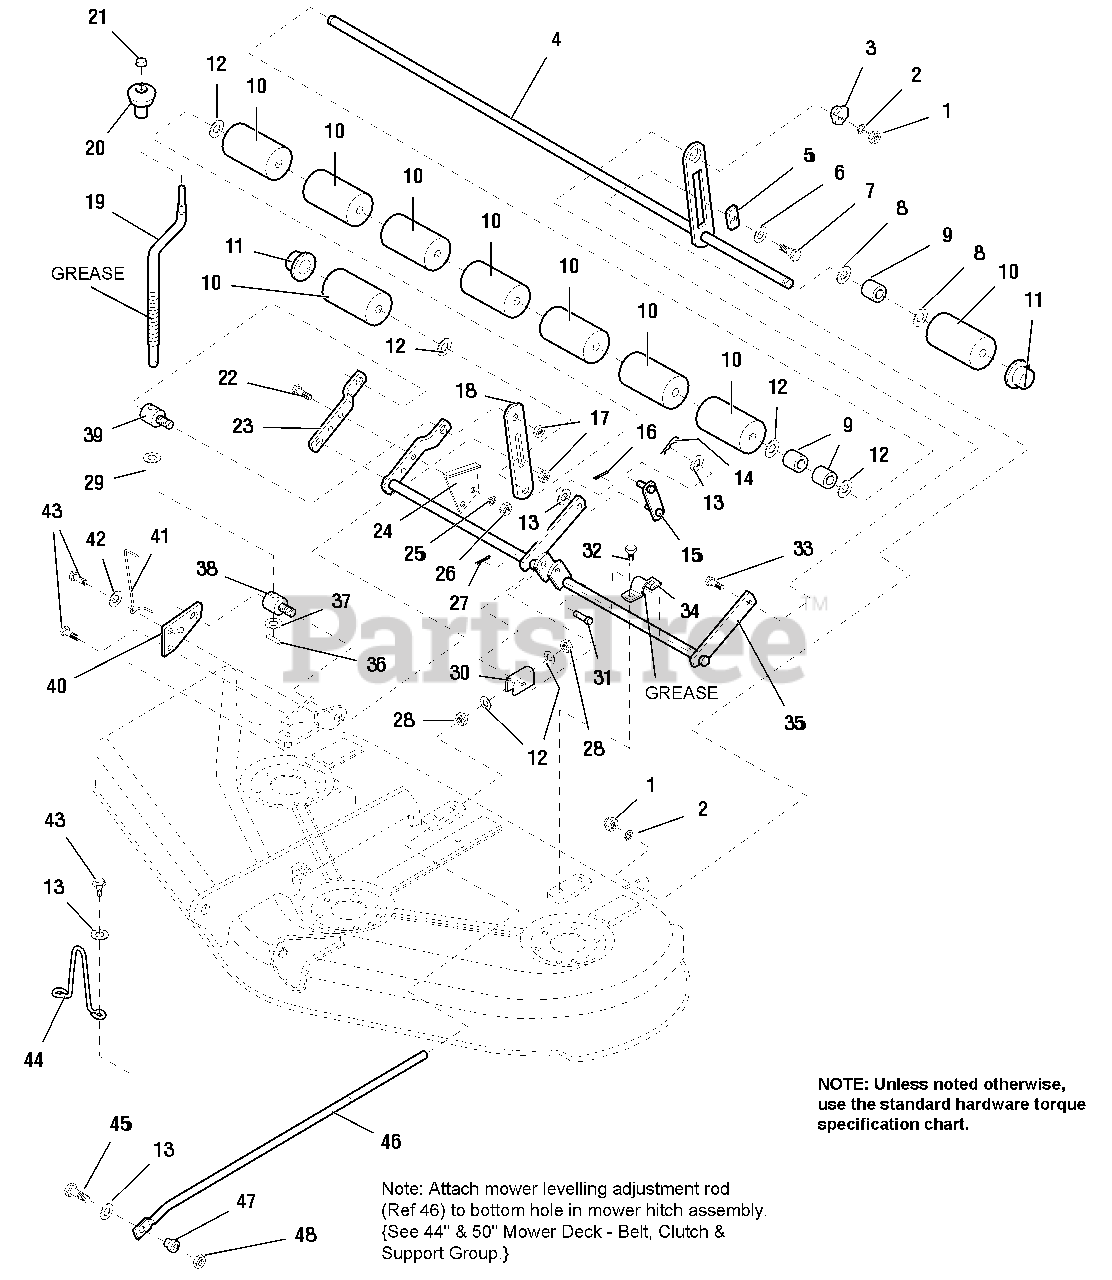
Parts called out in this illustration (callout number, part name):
1	NUT, Hex, 3/8-16
2	LOCKWASHER, 3/8
3	NUT, Hex Adjusting, .99 DIA .687
4	SHAFT ASSEMBLY, Roller, 50" (Includes Ref. No. 11)
6	WASHER, Plain, 1/2
7	BOLT, Shoulder, 3/8-16 X 1.34
8	WASHER, 5/8
11	NUT, Push
12	WASHER, 5/8
13	WASHER, Plain, 13/32
14	CLIP, Pin, Safety
15	LINK ASSEMBLY, Lift
17	NUT, Hex Flange Lock, 1/2-13
18	BAR, Roller
19	CRANK, Cutting Height
20	KNOB, Height Crank
21	PAL NUT
22	CAPSCREW, Hex Head, 5/16-18 x 1-1/4
23	ARM, Rear, Mower, RH
24	BRACKET, Cutting Height
26	NUT, Hex, 5/16-18 Whiz Lock
27	PIN, Hair Clip
28	NUT, Hex Jam, 3/4-11
29	WASHER, 5/8
30	TRUNNION
31	PIN, Clevis
32	CAPSCREW, Taptite, 5/16-18 x 3/4
33	CARRIAGE BOLT, 3/8-16 x 1-1/2
34	STRAP, Mower Arm Assembly
35	ARM ASSEMBLY, Mower
36	PIN, Roll, 1" Long
37	WASHER, Detent
39	TRUNNION, Threaded
40	PLATE, Mower Support
41	INDICATOR, Cutting Height
42	WASHER, Flat, 5/16
43	CAPSCREW, Taptite, 5/16-18 x 1-1/4
44	UP-STOP, Mower
45	CAPSCREW, Hex Head, 3/8-16 x 1-3/4
46	ROD, Adjustment
48	NUT, Hex Flange, 3/8-16
